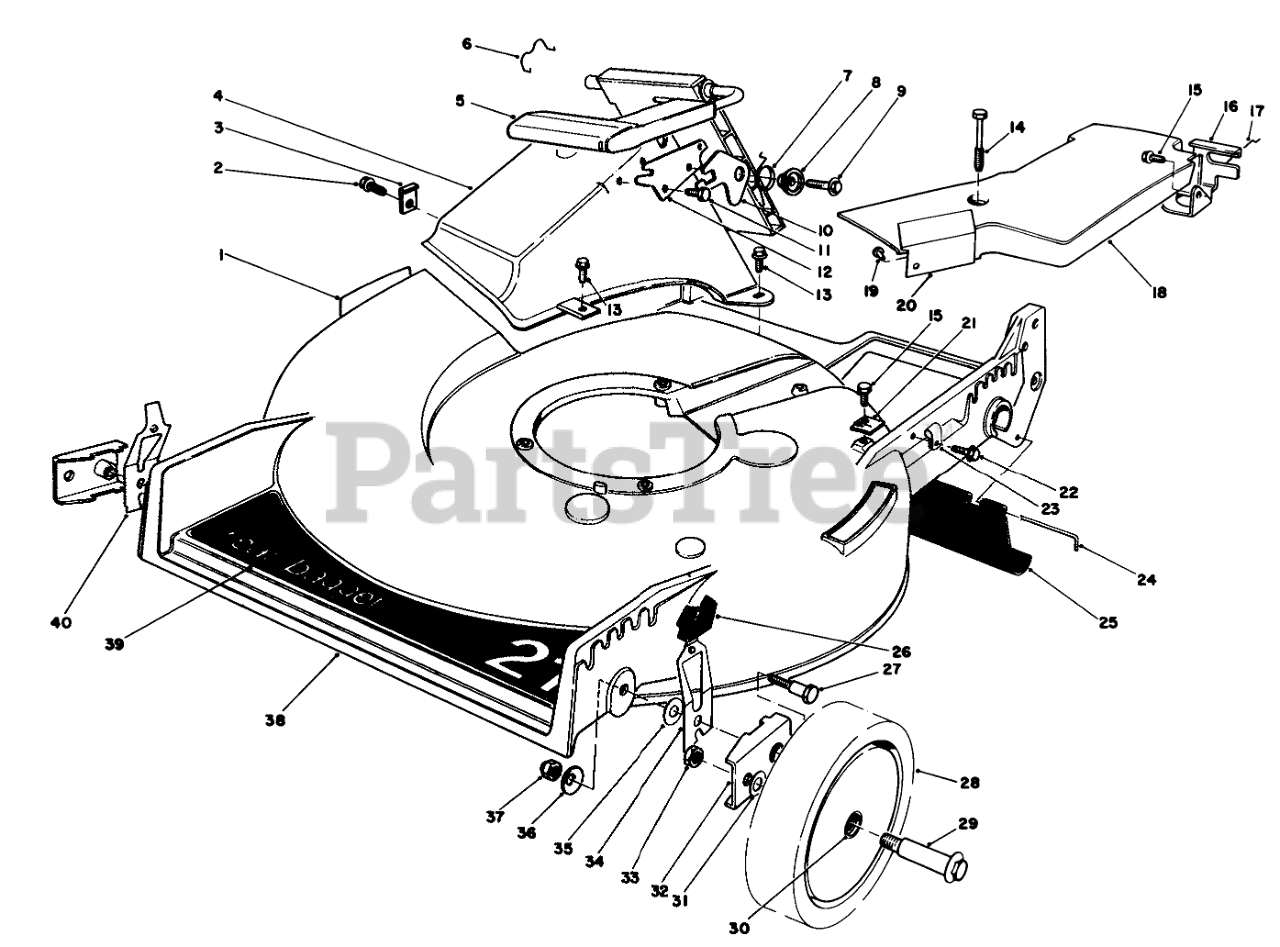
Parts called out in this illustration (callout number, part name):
1	DECAL-DANGER
2	SCREW
3	TUNNEL CLIP
4	Tunnel Discharge
5	Discharge Door Assembly
6	DOOR RET SPRING
7	TORSION SPRING
8	DOOR SPACER
9	SCREW-HWH
10	SAFETY LATCH
11	SCREW-PLASTITE
12	DOOR LATCH PLATE
13	SCREW-HWH
14	SCREW-HHFTF
15	SCREW-HWHTF
16	Bracket-Traction Adj.
17	RETAINER-CABLE
18	Belt Cover Assembly (Incl. Ref. #19 & 20)
19	RIVET-HEAD, FLAT
20	HEAT SHIELD
21	Cable Clamp
22	SCREW
23	CLAMP-CABLE
24	ROD-SHIELD
25	SHIELD-TRAILING
26	KNOB-ARM
27	PIVOT SCREW
28	Wheel & Tire Assembly (Incl. Ref. #30)
29	WHEEL BOLT
30	BUSHING
31	WASHER
32	HP PIVOT ARM ASM
33	NUT-LOCK
34	L. HP SPRING ARM ASM
35	WASHER-PIVOT
36	WASHER-BELLEVILLE
37	NUT-LOCK, NI
38	Housing (Incl. Ref. #1)
39	DECK DECAL
40	R HP SPRING ARM ASM
